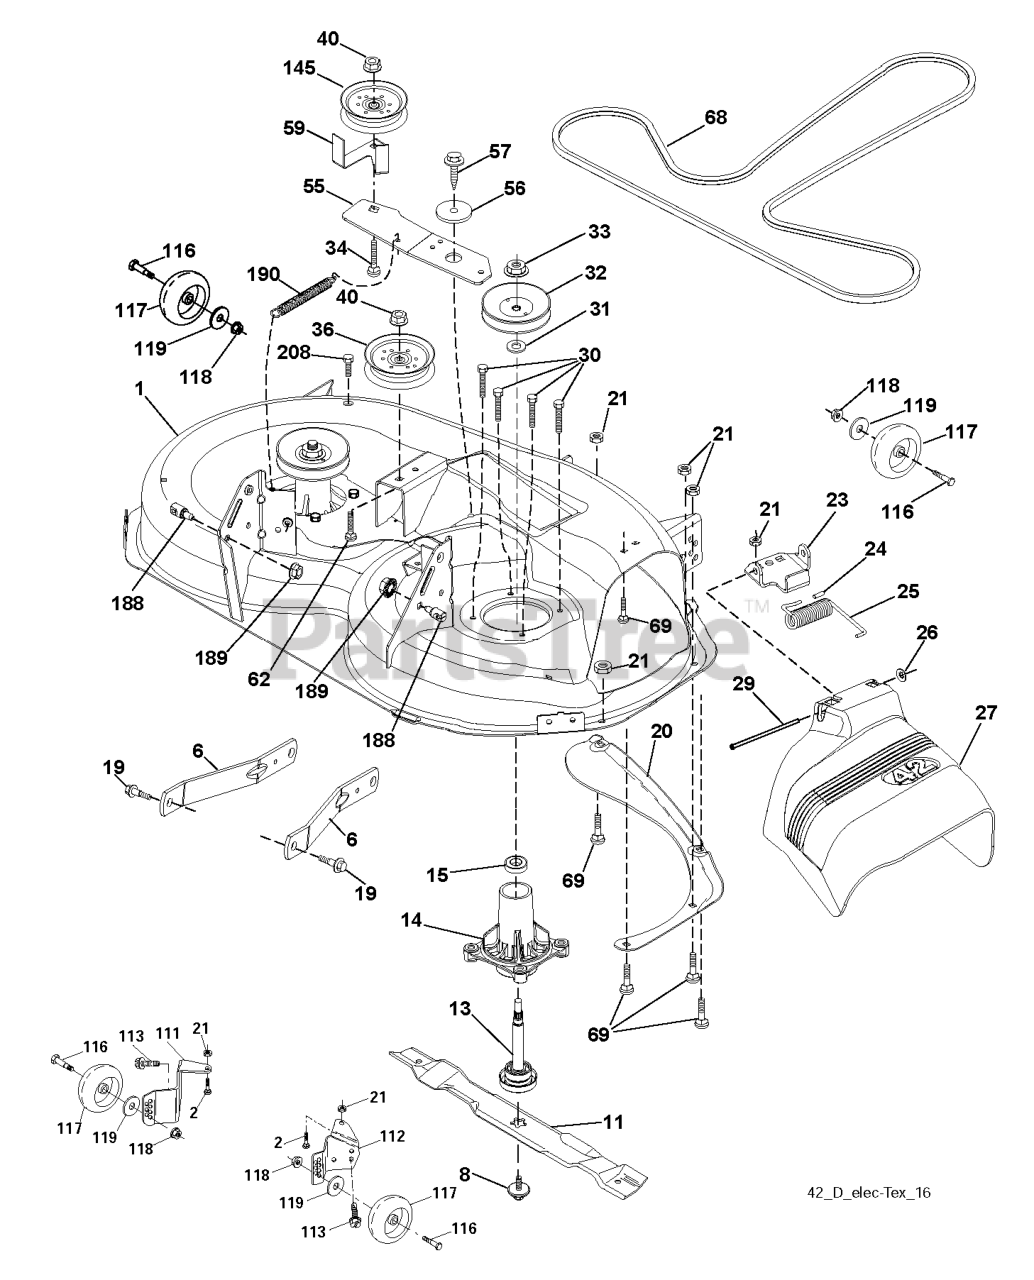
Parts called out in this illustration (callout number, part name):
1	DECK.WELDMENT.42"PAINT
2	RP BOLT 5/16-18 X3/4 ZN/YEL GR
6	ARM.SUSPENSION.MOWER.R
8	BOLT.WASHER.ASM.7/16-2
11	42" HI-LIFT BLADE
13	SHAFT.ASM.MDRL.N/GREASE.38
14	RP.HOUSING.MANDREL.4PT.
19	BOLT.SHOULDER
20	BAFFLE.VORTEX
21	LOCKNUT
23	BRKT.DEFLECTOR.38"2005+
24	CAP-SLEEVE LT
25	SPRING.TORSION.DEFLECT
26	NUT PUSH M
27	SHIELD.DEFLECTOR.MOWER.42"BLAC
29	ROD.HINGE
30	SCREW, WASHER HEAD
31	WASHER.SPACER.MANDREL
32	PULLEY/MANDREL
33	NUT.FLANGE.LOCK.TOP
34	BOLT.3/8-16X1.50
36	PULLEY.IDLER.2006
40	NUT LOCK FLG 3/8-16 UNC
56	SPACER.RETAINER
57	SCREW 3/8-16X1
59	GUARD, BELT
68	BELT V SECONDARY
69	BOLT
111	BRKT.WHEEL.GAUGE.LH.42"
112	BRKT.WHEEL.GAUGE.RH.42"
113	BOLT.5/16HEX.WHS.HD
116	BOLT M
117	WHEEL.GAGE.HALF.SPOKED
118	LOCKNUT
119	WASHER.5/16.FLAT.STE.STD.
145	PULLEY.IDLER.48"PRIMARY
188	STUD.FASTNER.W/ANTI-ROTATE
189	NUT LOCK HEX FLANGE 5/16-18
190	SPRING.MOWER.DRIVE.ELECTRIC
208	SCREW 3/8-16X1/2
